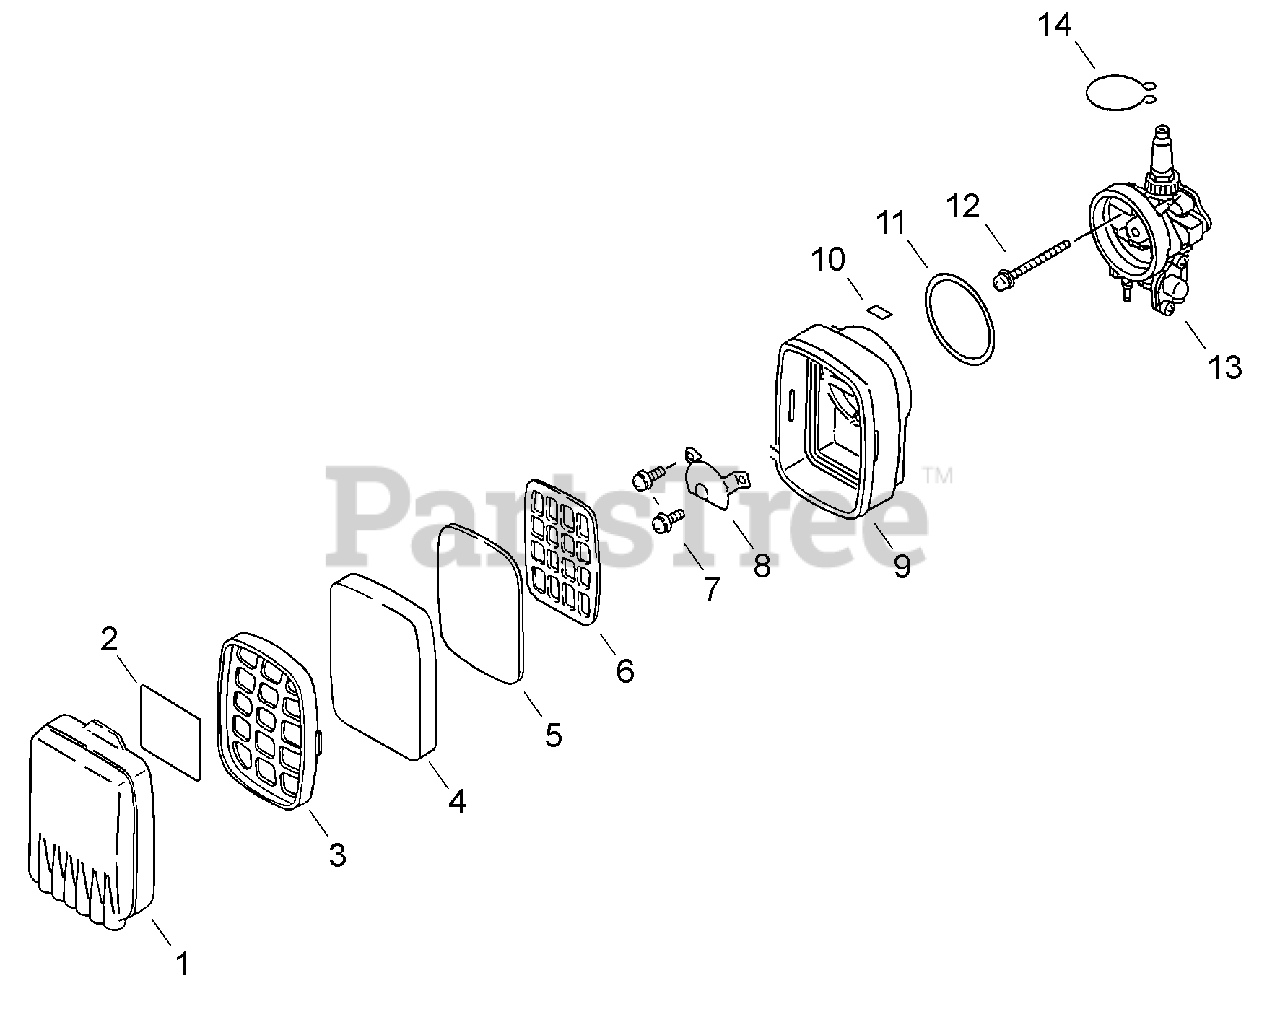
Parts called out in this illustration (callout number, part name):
1	COVER, AIR FILTER
2	LABEL, AIR FILTER
3	GRID, PRE-FILTER
4	PRE-FILTER, FOAM
5	FILTER, AIR
6	GRID, AIR FILTER
7	SCREW 4×14
8	PLATE, PREVENT
9	CASE, AIR FILTER
10	LABEL, CHOKE
11	GASKET, INTAKE
12	SCREW 5×55
13	CARBURETOR
14	CLIP, TUBE
